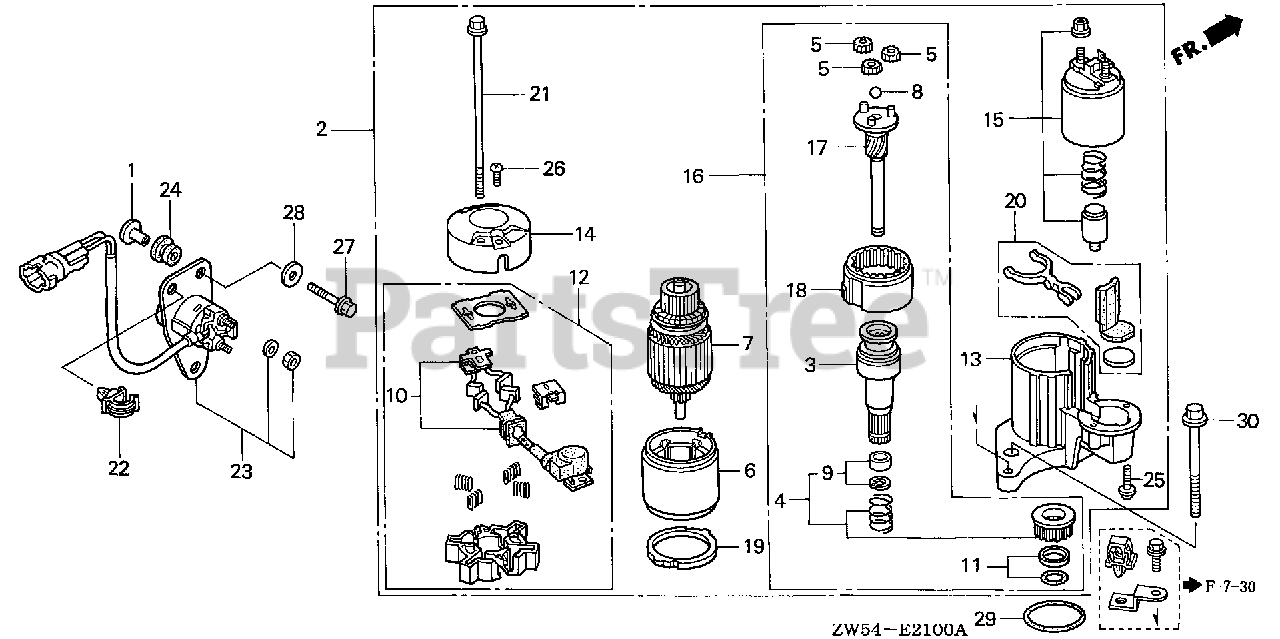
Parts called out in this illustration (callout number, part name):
1	COLLAR, FUEL TANK MOUNTING
2	STARTER MOTOR ASSY.
3	CLUTCH, OVERRUNNING
4	GEAR SET, PINION
5	GEAR ASSY., PLANETARY
8	BALL, STEEL
9	STOPPER SET, PINION
11	STOPPER SET, SLEEVE
12	HOLDER, BRUSH
13	BRACKET, FR.
14	BRACKET, RR.
15	SWITCH ASSY., MAGNET
16	SHAFT ASSY., CLUTCH
17	SHAFT ASSY., GEAR
18	GEAR ASSY. (INNER)
21	BOLT A, THROUGH
22	CLAMP, WIRE
23	SWITCH ASSY., STARTER MAGNETIC
24	RUBBER A, NUMBER BRACKET CUSHION
25	SCREW, PAN (6X22) (SPECIAL)
26	SCREW, PAN (5X8)
27	BOLT, FLANGE (6X25)
28	WASHER, PLAIN (6MM)
29	O-RING (54.4X3.1)
30	BOLT, FLANGE (10X35)
